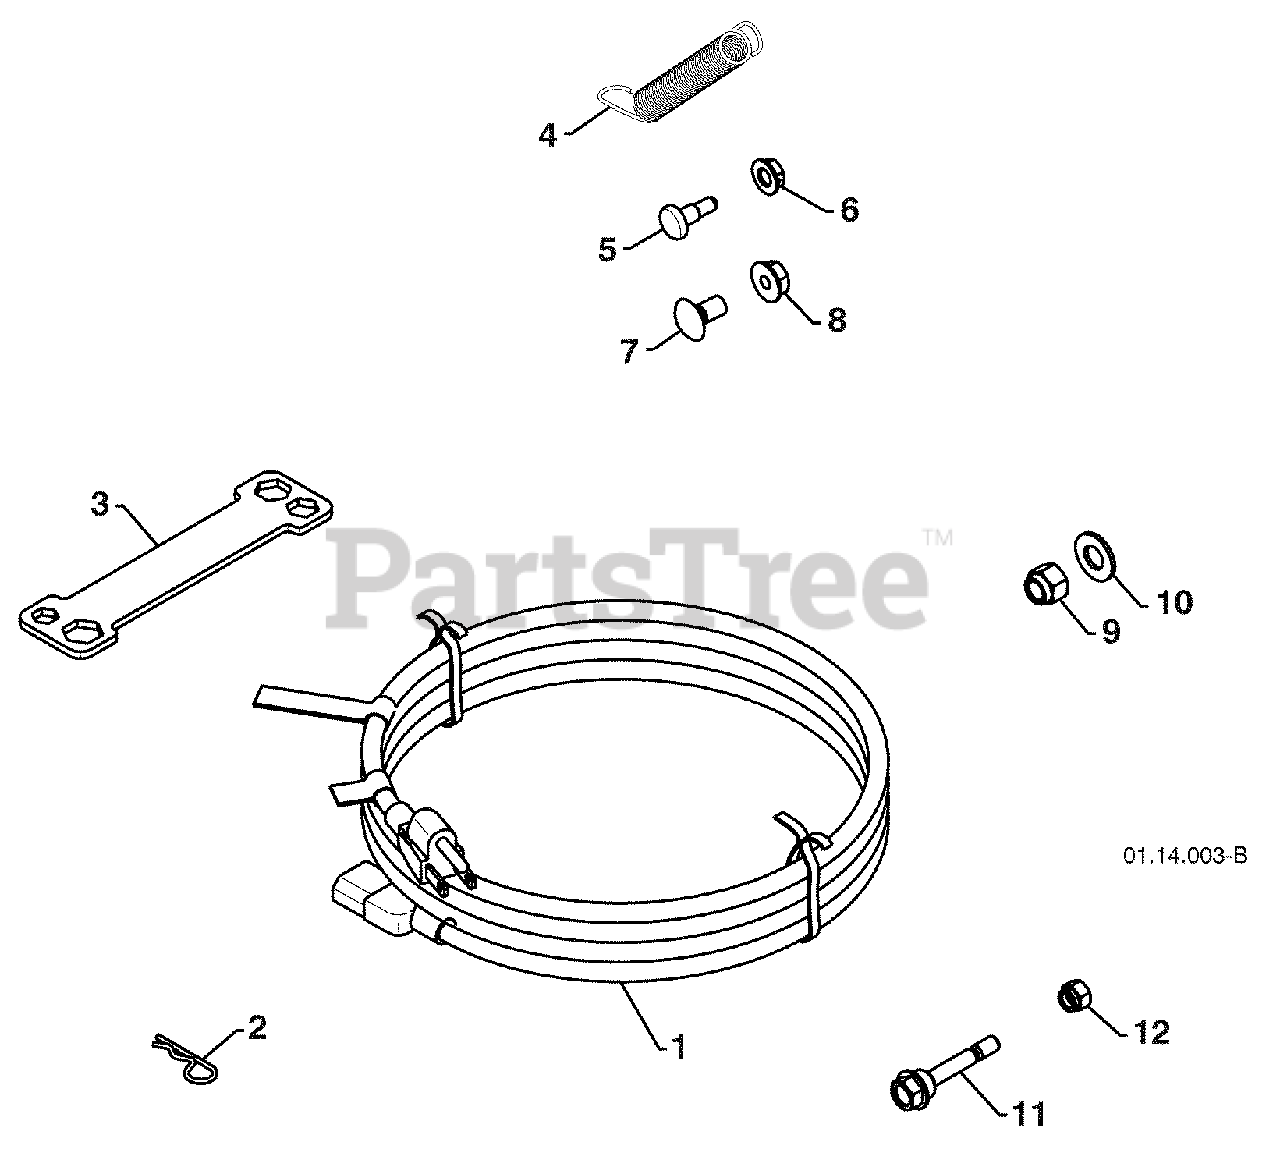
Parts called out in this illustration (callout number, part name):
1	POWER CORD
2	RETAINER PIN
4	REMOTE SPRING
5	SHOULDER BOLT 1/4-20
6	LOCKNUT 1/4-20
7	CARRIAGE BOLT 5/16-18 X 5/8
8	LOCKNUT 5/16-18
9	LOCKNUT 3/8-16
10	WASHER 3/8
11	SHEAR BOLT 1/4-20 X 1-13/16
12	LOCKNUT 1/4-20
